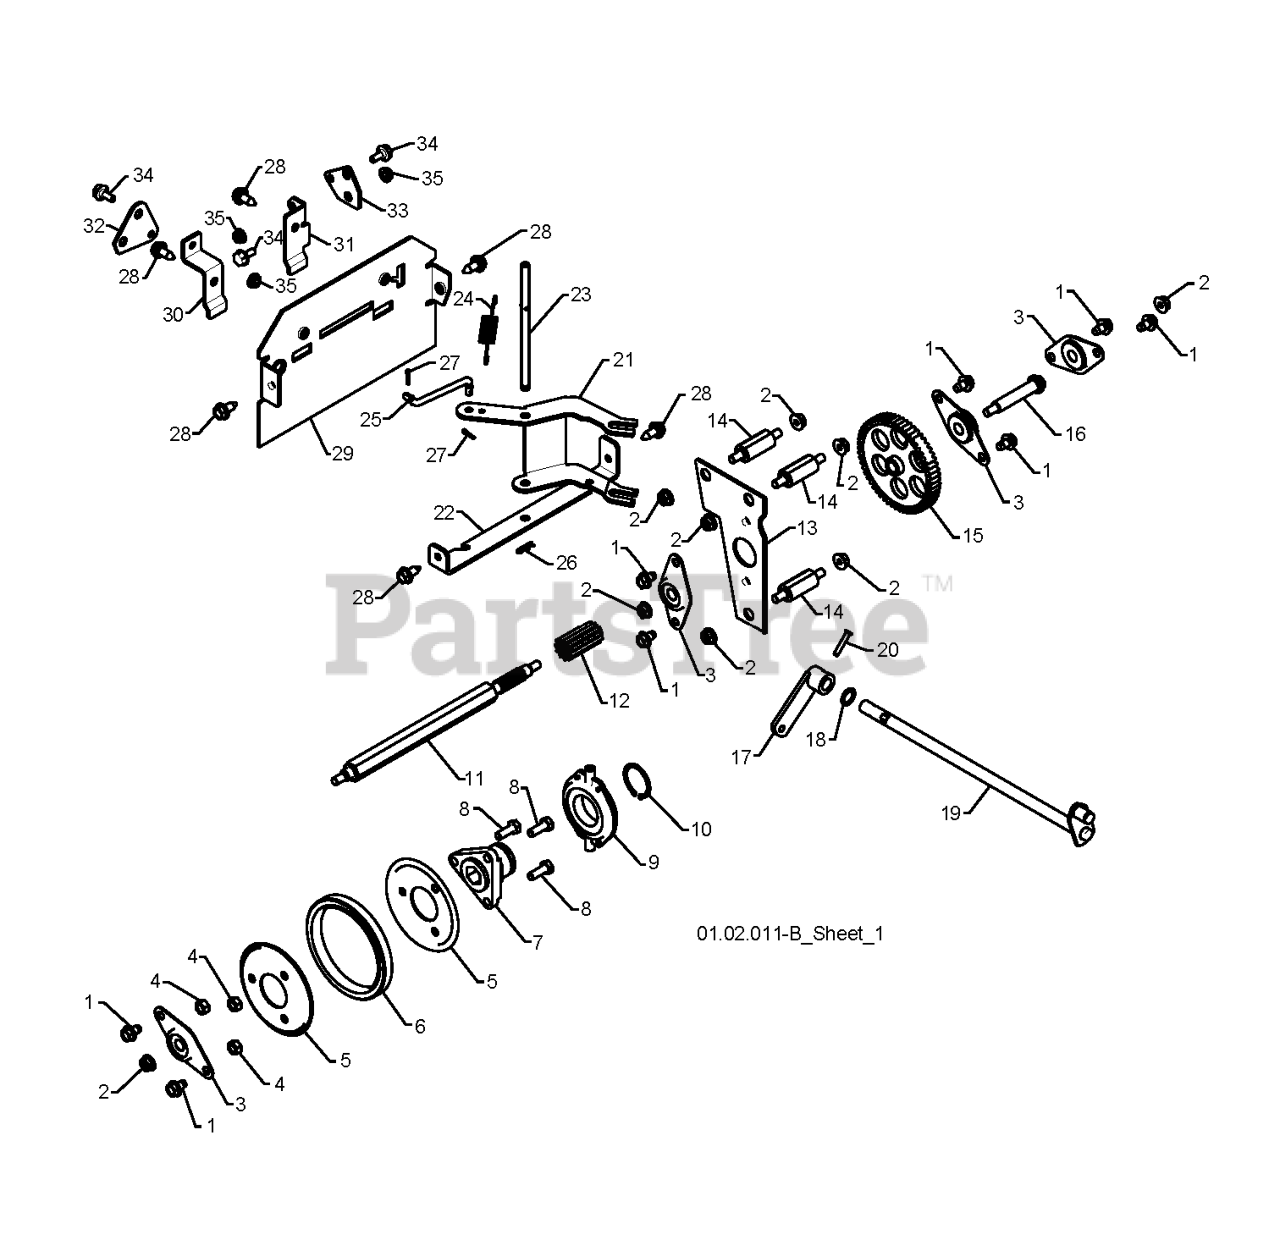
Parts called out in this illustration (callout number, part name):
1	Screw 5/16-18 x 1/2 Hex, Self Tapping 5/16-18 x 1/2
2	NUT.LOCK.5/16-18
3	BEARING, FLANGE
4	NUT.CENTERLOCK.5/16-
5	PLATE.RUBBER.WHEEL.BLACK
6	RING, RUBBER WHEEL
7	HUB, RUBBER WHEEL
8	BOLT
9	TRUNNION BEARING ASSY
10	RETAINING RING (2 2)(3 2)
11	SHAFT.HEX.LONG
12	GEAR, PINION
13	PLATE.AUXILIARY.
14	SPACER, PLATE
15	GEAR, INTERMEDIATE
16	SHAFT, AUXILIARY
17	ARM, AUGER CONTROL
18	THRUST WASHER
19	CONTROL.SHAFT.ASM
20	CLEVIS PIN
21	RP SHIFTER LEVER
22	BRACKET.SHIFT.PIVOT.BLACK
23	PIN, PIVOT
24	SPRING, BIAS
25	LINK, SPEED CONTROL
26	RETAINER CLIP PM
27	RETAINER CLIP
28	BOLT.HEX.HD.WASHER.5/16-18X.75
29	PLATE.REAR.SNOW.PNT.ORANGE
30	RP BRACKET.SHIFTER.PLATE
31	BRACKET.CLUTCH.PLATE
32	RP PLATE.SHIFTER.
33	LATE.CLUTCH.
34	BOLT.SHOULDER.3/X.25
35	NUT.HEX.FLANGE.1/4
